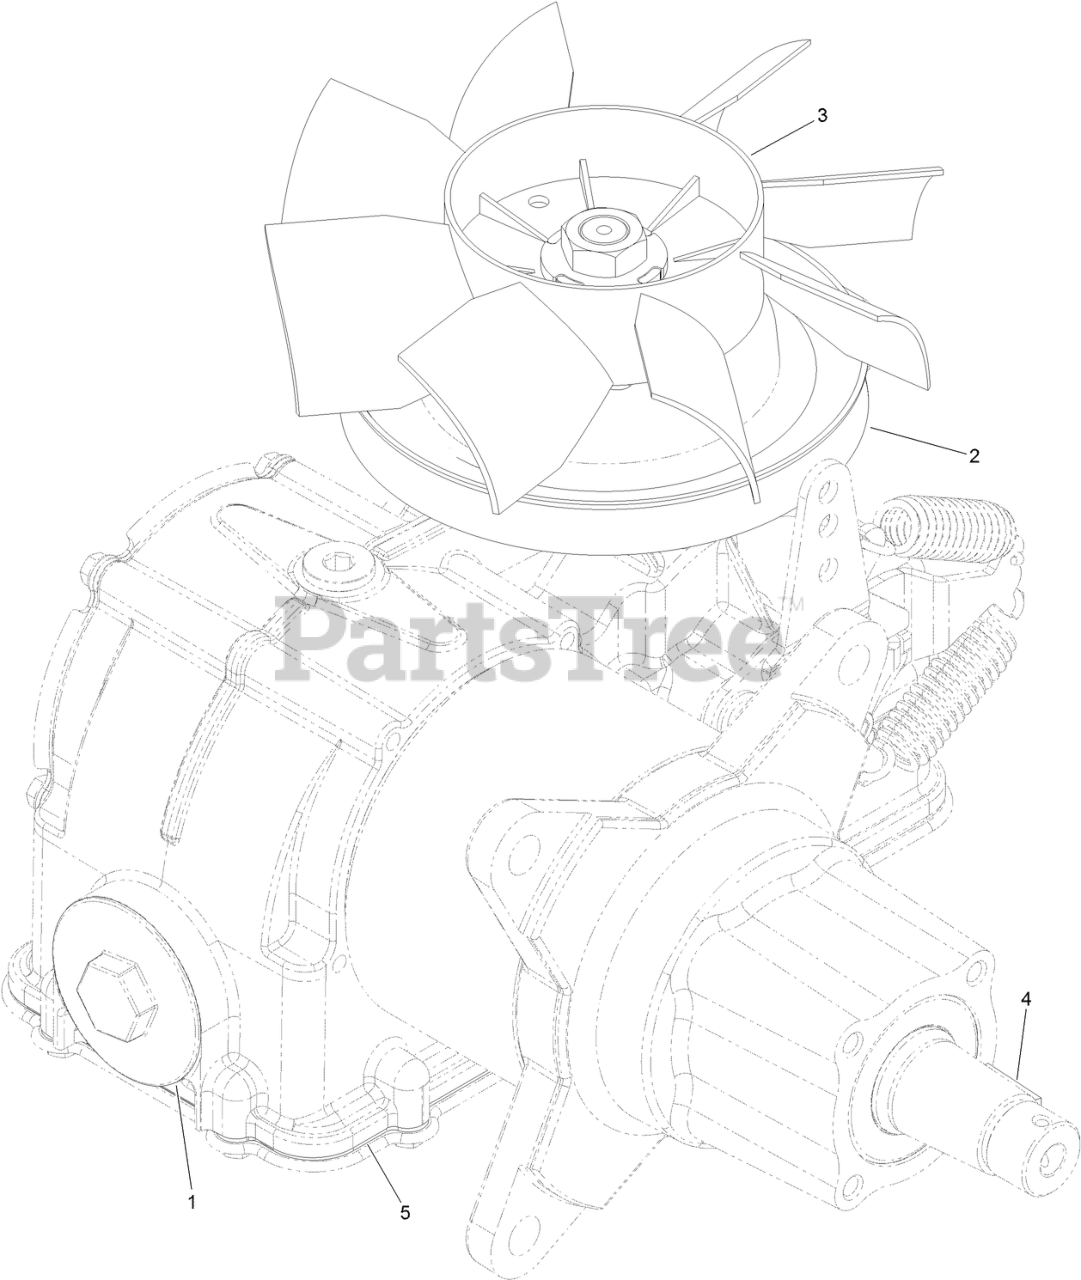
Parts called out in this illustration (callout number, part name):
1	FILTER
2	PULLEY
3	FAN (8.3 INCH)
4	KEY-WOODRUFF
5	GASKET-COVER, BOTTOM
